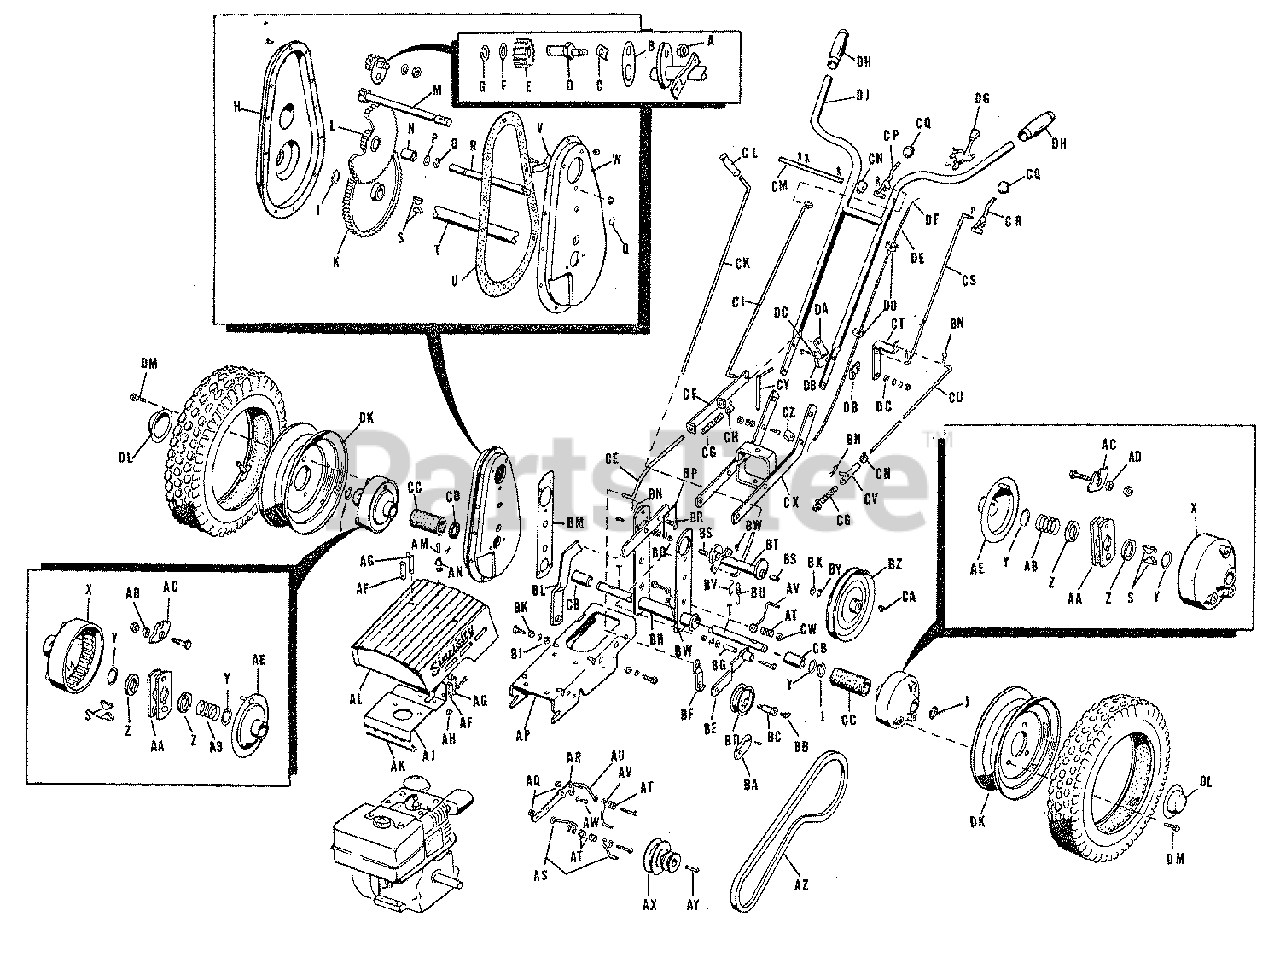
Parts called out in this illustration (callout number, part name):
A	NUT, Hex, Full, L.H.
D	STUD, Reverse Pinion
E	PINION ASSEMBLY, Reverse with Bearing
F	WASHER, Reverse Pinion
G	RING, Retainer
H	COVER, Gear Case
J	RING, Retainer
K	GEAR, Drive
L	*GEAR ASSEMBLY, Intermediate
M	PINION AND PULLEY SHAFT ASSEMBLY
N	BEARING, Intermediate Pinion
Q	RING, Retainer
R	SHAFT, Intermediate
S	KEY, Hi-Pro, HP-608
U	GASKET, Gear Case
V	SPRING, Drag
W	CASE, Gear
X	HUB, Wheel
Z	WASHER, Axle
AA	CAGE ASSEMBLY, Ratchet
AB	SPRING, Axle
AE	COVER ASSEMBLY, Ratchet Cage
AF	LATCH, Stub
AH	NUT, Hex, Full, Lock, 1/4-20 NC
AJ	BRACKET ASSEMBLY, Hood
AK	PIN, Hinge
AL	HOOD ASSEMBLY
AM	PIN, Hood
AN	SPRING, Hood
AQ	NUT, Hex, Jam, 5/16-18 NC
AR	HOLDER, Belt Stop
AS	STOP, Belt
AU	STOP, Belt
AV	STOP, Belt
AW	SCREW, Holder
AX	PULLEY, Engine
AY	KEY, Engine Pulley
AZ	BELT, "V", 46" Long
BA	PLATE, Serial No.
BB	FITTING, Grease, Alemite #1911
BC	PIN, Idler Pulley
BD	PULLEY ASSEMBLY, Idler
BE	LEVER ASSEMBLY, Idler
BF	EXTENSION, Idler Lever
BG	SPACER, Idler Lever
BH	HOUSING ASSEMBLY, Axle
BJ	NUT, Hex, Full Lock, 3/8-16 NC
BK	SPACER, Lock Bar
BL	BAR, Lock
BM	GASKET, Bearing Housing
BN	CLIP, Spring
BQ	NUT, Hex, Jam, 5/16-18 NC
BT	HOUSING ASSEMBLY, Bearing
BU	SPRING, Reverse Lever
BV	EXTENSION, Spring
BW	FITTING, Grease, Alemite #1641
BY	RING, Retainer
BZ	PULLEY, Transmission
CA	KEY, Woodruff, #9
CB	BEARING, Axle
CC	TUBE, Rubber
CD	WASHER, Retainer
CE	ROD, Clutch, Lower
CF	GUIDE ASSEMBLY, Clutch Rod
CH	COLLAR, Set
CJ	ROD, Clutch, Upper
CK	ROD, Reverse
CL	GRIP, Reverse Rod
CM	SHAFT, Lever
CN	GUIDE, Reverse Rod
CP	LEVER ASSEMBLY, R.H.
CQ	BALL, Clutch Lever
CR	LEVER ASSEMBLY, L.H.
CS	ROD, Upper Idler
CT	LEVER, Lower Clutch
CU	ROD, Lower Clutch
CV	SOCKET ASSEMBLY, Rod
CW	NUT, Lock, Full, Hex, 3/8-16
CX	FRAME ASSEMBLY
CY	PIN ASSEMBLY, Hitch
CZ	CLAMP, Cable
DA	LEVER, Pivot
DB	STOP, Lever
DD	CLIP, Cable
DE	CABLE, Throttle
DF	CONTROL, Throttle
DG	CONTROL, Throttle
DH	GRIP, Handle
DJ	HANDLE ASSEMBLY
DK	WHEEL, Less Tire and Tube
